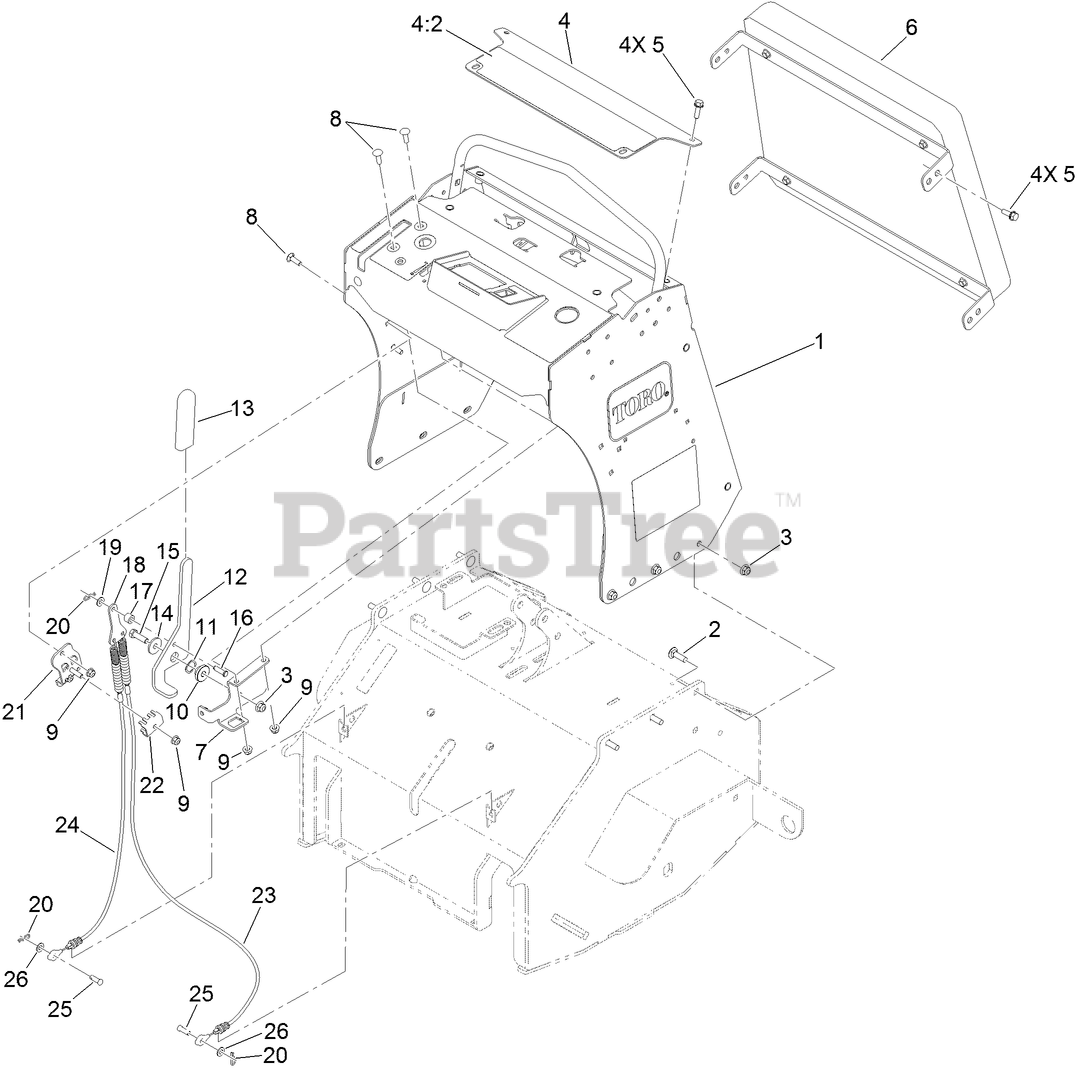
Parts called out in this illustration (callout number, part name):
1	CONTROL TOWER ASM
2	BOLT-CARR
3	NUT-HF, NI
4	CONTROL PANEL ASM
4:2	DECAL-WARNING
5	SCREW-HHF
6	CUSHION ASM
7	BRACKET-PIVOT, BRAKE
8	SCREW-CARR
9	NUT-HF, NI
10	PIVOT-FLANGE
11	WASHER-WAVE
12	HANDLE-BRAKE
13	GRIP-LEVER
14	WASHER
15	SCREW-HH
16	PIN-YOKE
17	BUSHING
18	YOKE-CABLE
19	SPACER-NYLON
21	MOUNT-CABLE, BRAKE
22	CLAMP-CABLE
23	CABLE-BRAKE, LH
24	CABLE-BRAKE, RH
25	PIN-CLEVIS
26	WASHER-PLAIN
